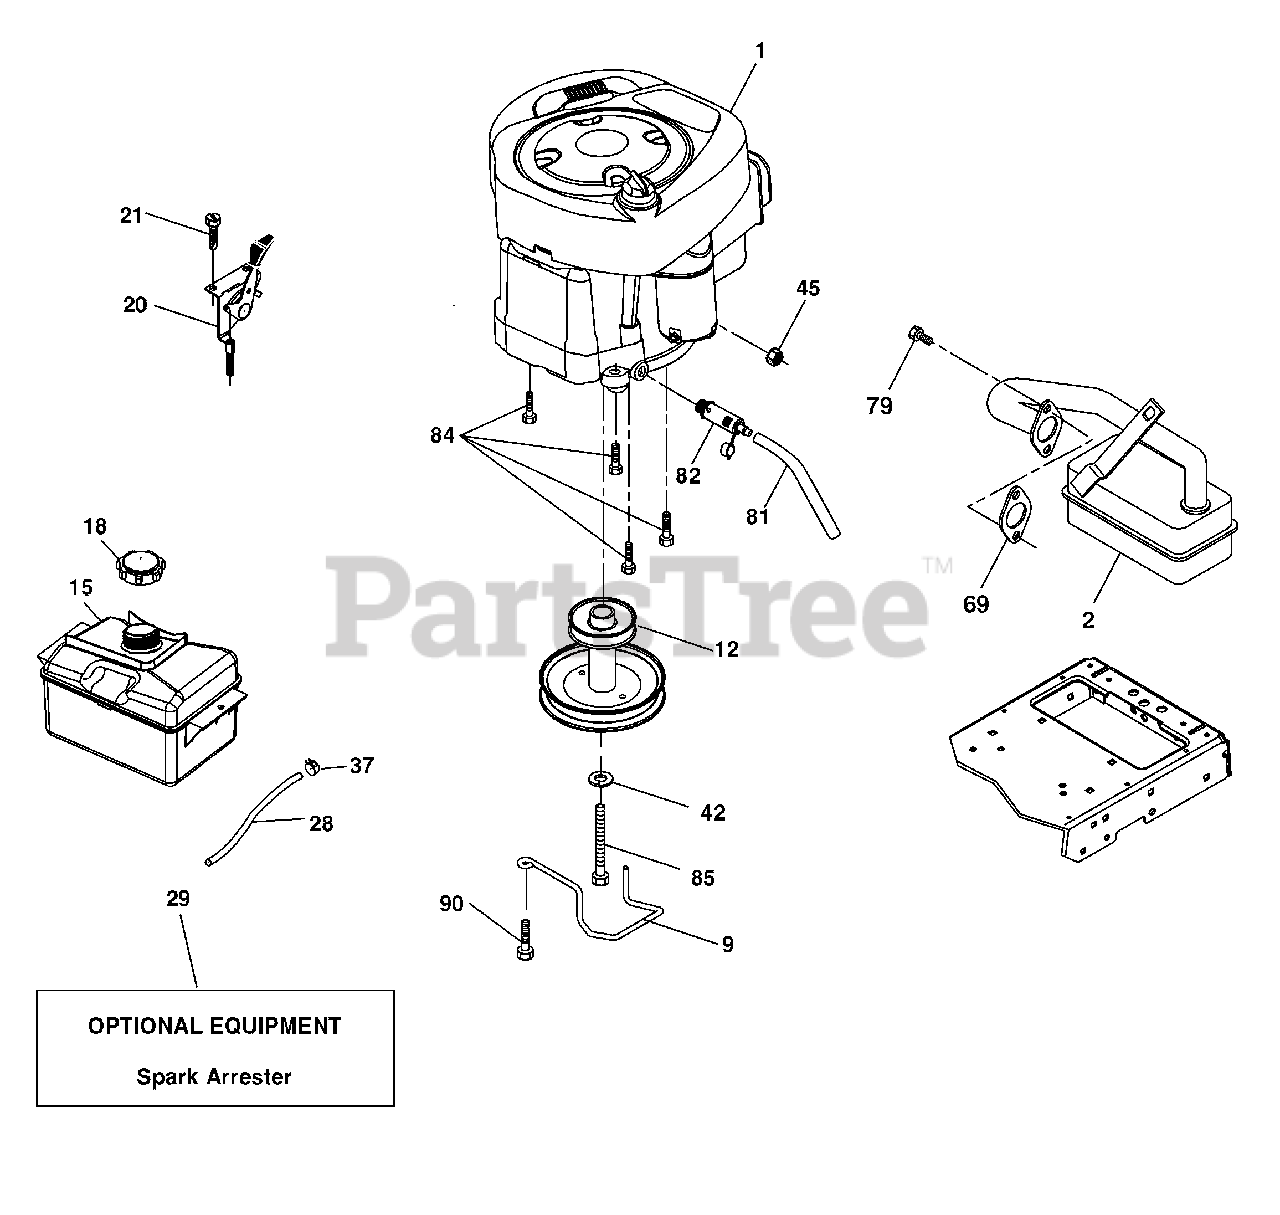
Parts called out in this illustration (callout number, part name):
9	Keeper Belt Engine
12	Pulley Engine
15	Tank Fuel
18	Cap Asm
20	Control Throttle/Choke
21	Screw 10 x 3/4 Single Lead Hex
28	Fuel Line
29	Spark Arrester Kit
37	Clamp Hose
42	Washer Lock 7/16
45	Nut Keps Hex 1/4-20 unc
69	Gasket
79	Screw Socket Hd. 5/16 - 18 x .75
81	Tube Drain Oil Easy
82	Plug Drain Oil
84	Screw 3/8-16 x 1-1/4
85	Bolt 5/16 - 20 x 4 x Gr. 5 - 1.5
90	Screw 3/8-16 x 1
